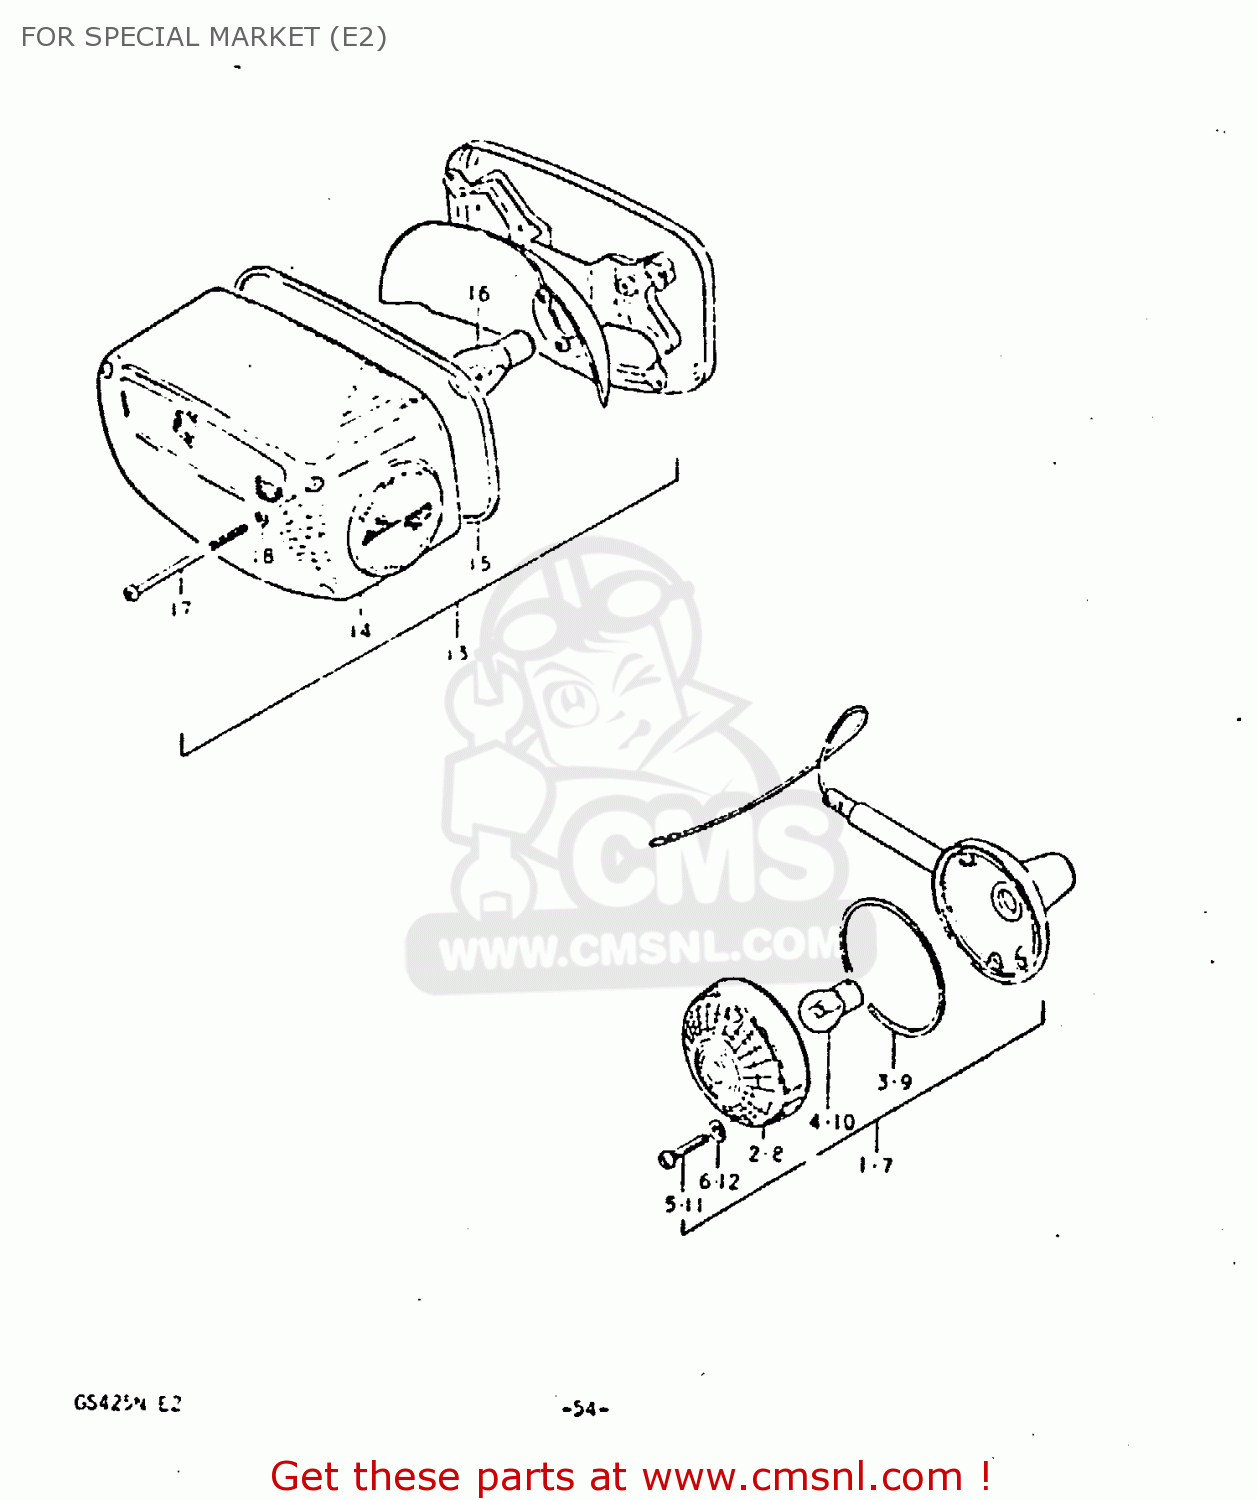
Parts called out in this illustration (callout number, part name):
1	LAMP ASSY, FRONT TURN SIGNAL
2	LENS
3	GASKET (NAS)
4	BULB 12V 21W
5	SCREW
6	GASKET (NAS)
7	LAMP ASSY, REAR TURN SIGNAL
8	LENS
9	GASKET (NAS)
10	BULB 12V 21W
11	SCREW
12	GASKET (NAS)
13	LAMP ASSY, REAL COMBINATION
14	LENS,REAR COMBINATION LAMP
15	GASKET (NAS)
16	BULB
17	SCREW (4X55)
18	GASKET (NAS)
